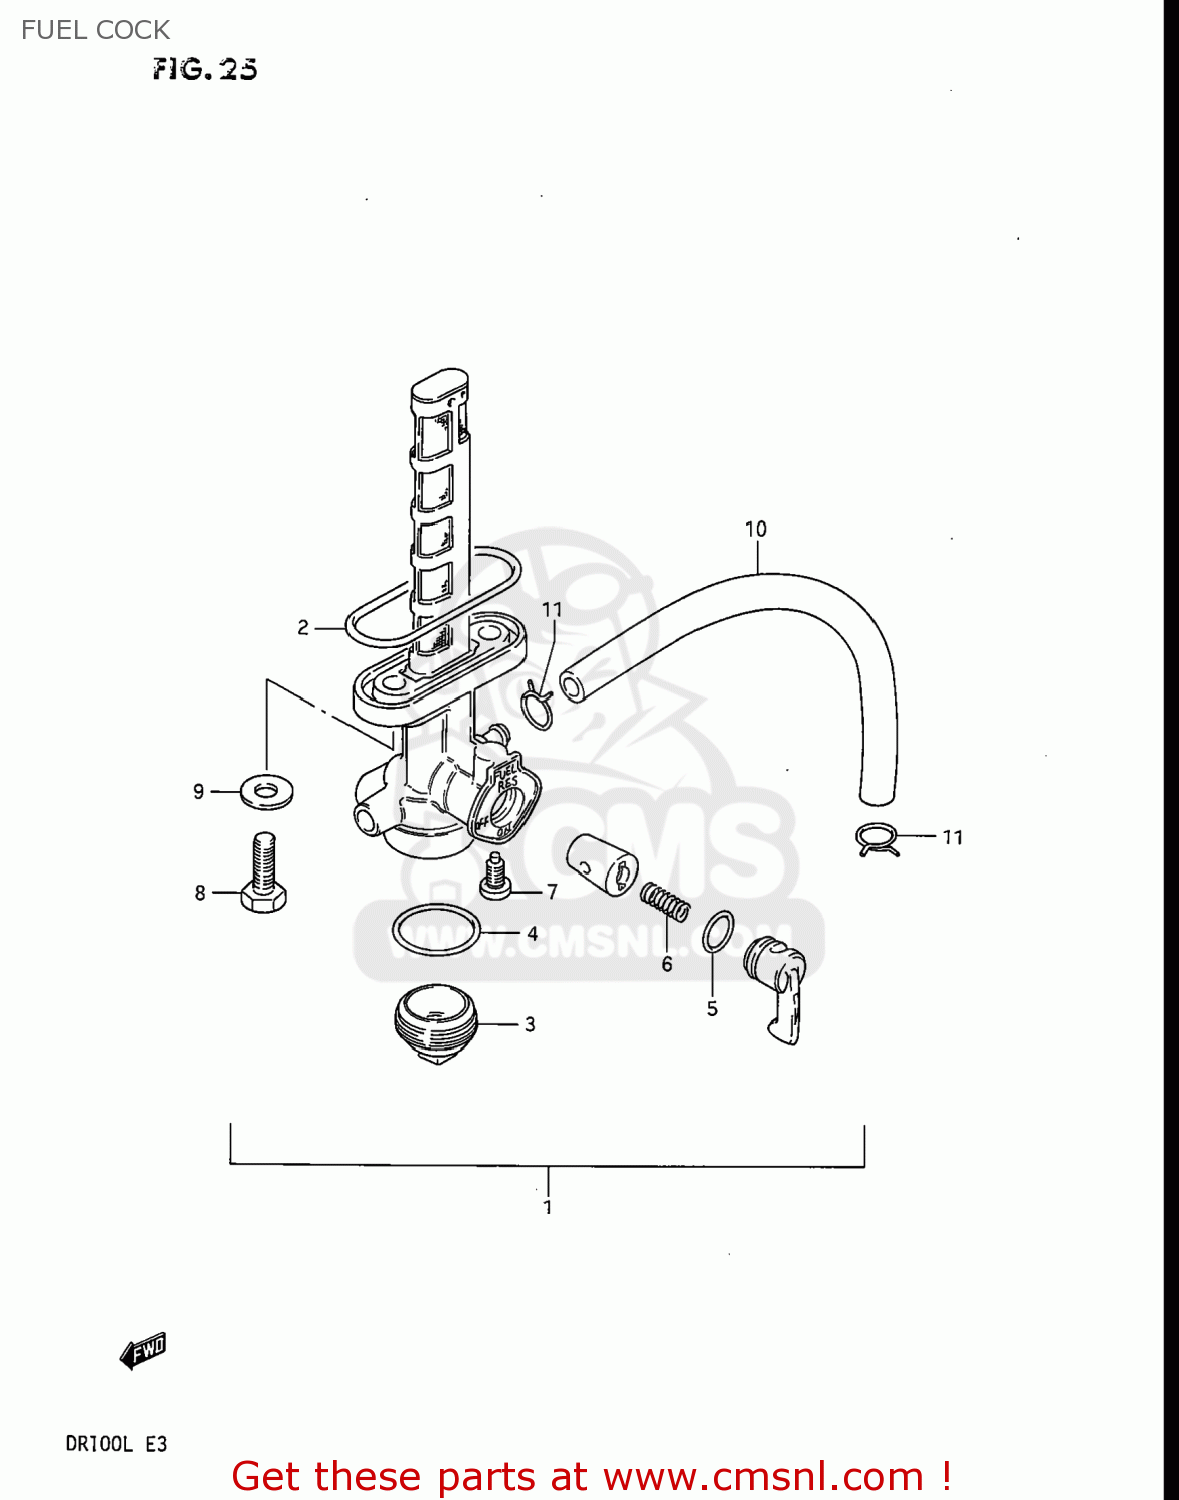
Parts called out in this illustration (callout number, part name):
1	COCK ASSEMBLY,FUEL
2	O RING,FUEL COCK
3	CUP,STRAINER
4	GASKET,FILTER (NAS)
5	O-RING
6	SPRING
7	SCREW
8	BOLT(6X20)
9	GASKET(6.4X11.5X0.8) (NAS)
10	HOSE
11	CLIP
